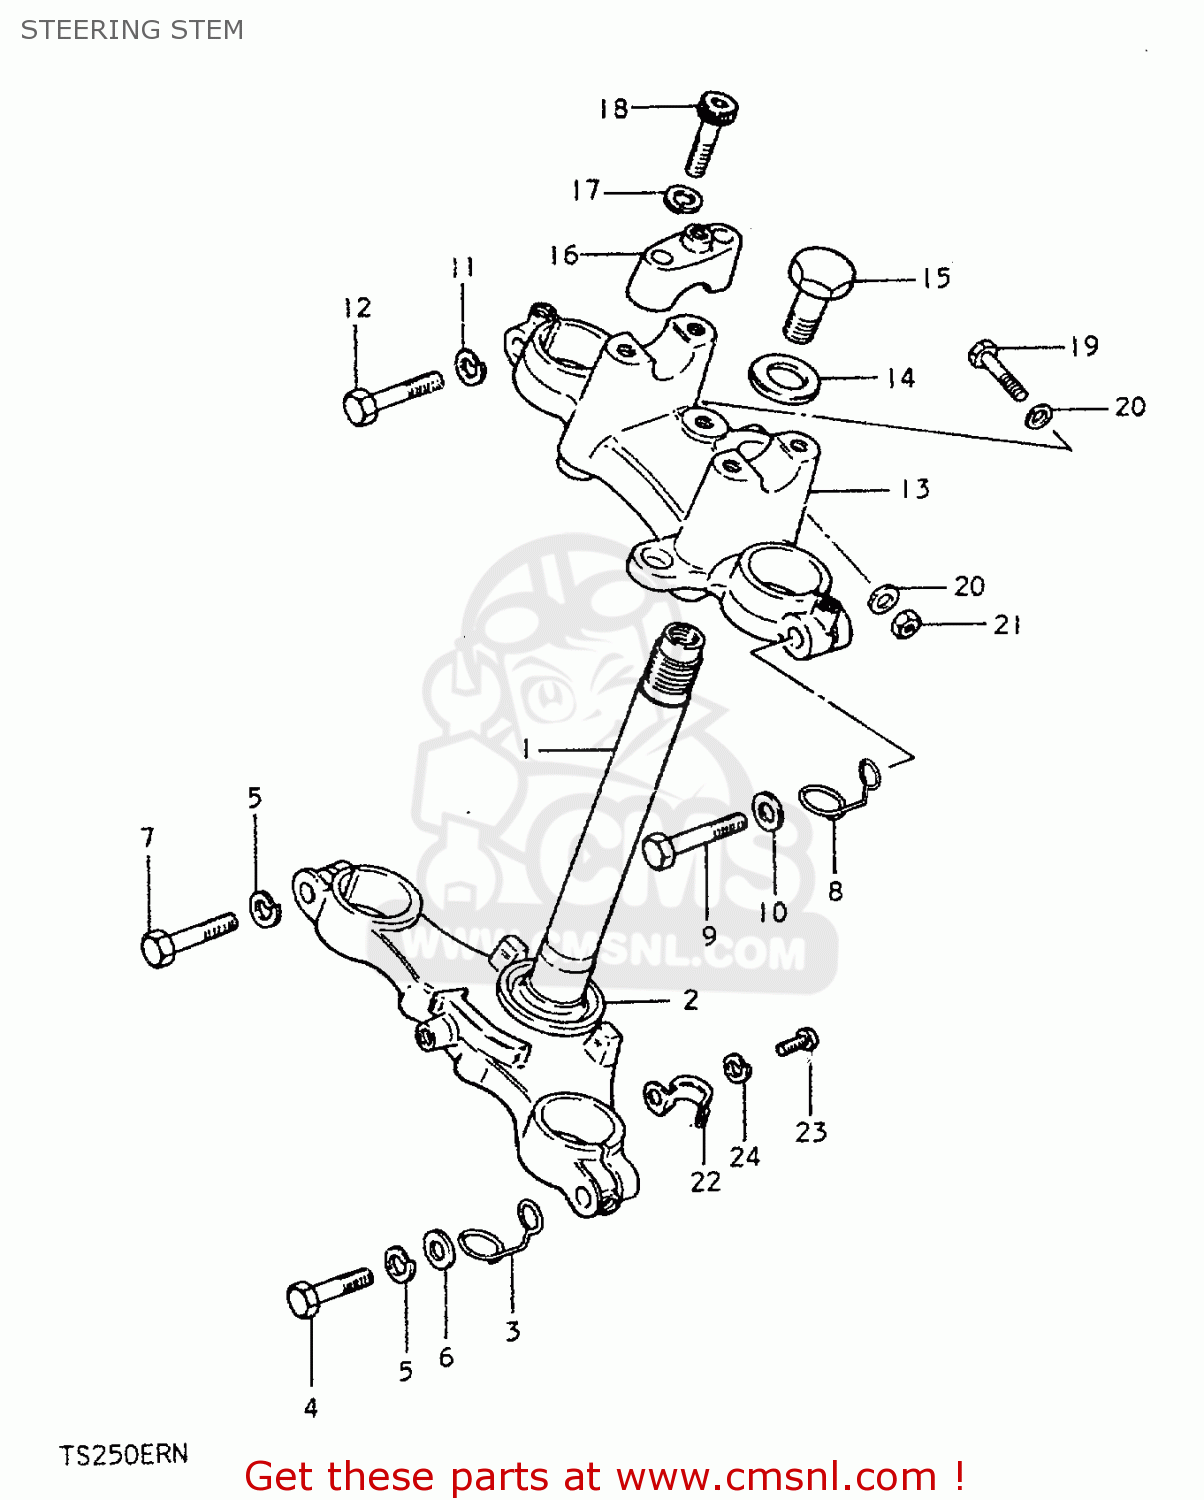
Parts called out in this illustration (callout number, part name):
1	STEERING STEM
2	RACE,STEERING OUTER LWR
3	CLIP
4	BOLT
5	WASHER,LOCK 12
6	WASHER
7	BOLT
8	CLIP
9	BOLT 10X40
10	WASHER
11	LOCK WASHER
12	BOLT 10X40
13	HEAD,STEERING STEM
14	WASHER
15	BOLT,STEERING STEM HEAD
16	CLAMP,HANDLE HOLDER UPR
17	LOCK WASHER
18	BOLT 8X35
19	BOLT 8X55
20	WASHER
21	NUT
22	CLIP,BRAKE CABLE
23	SCREW
24	LOCK WASHER
